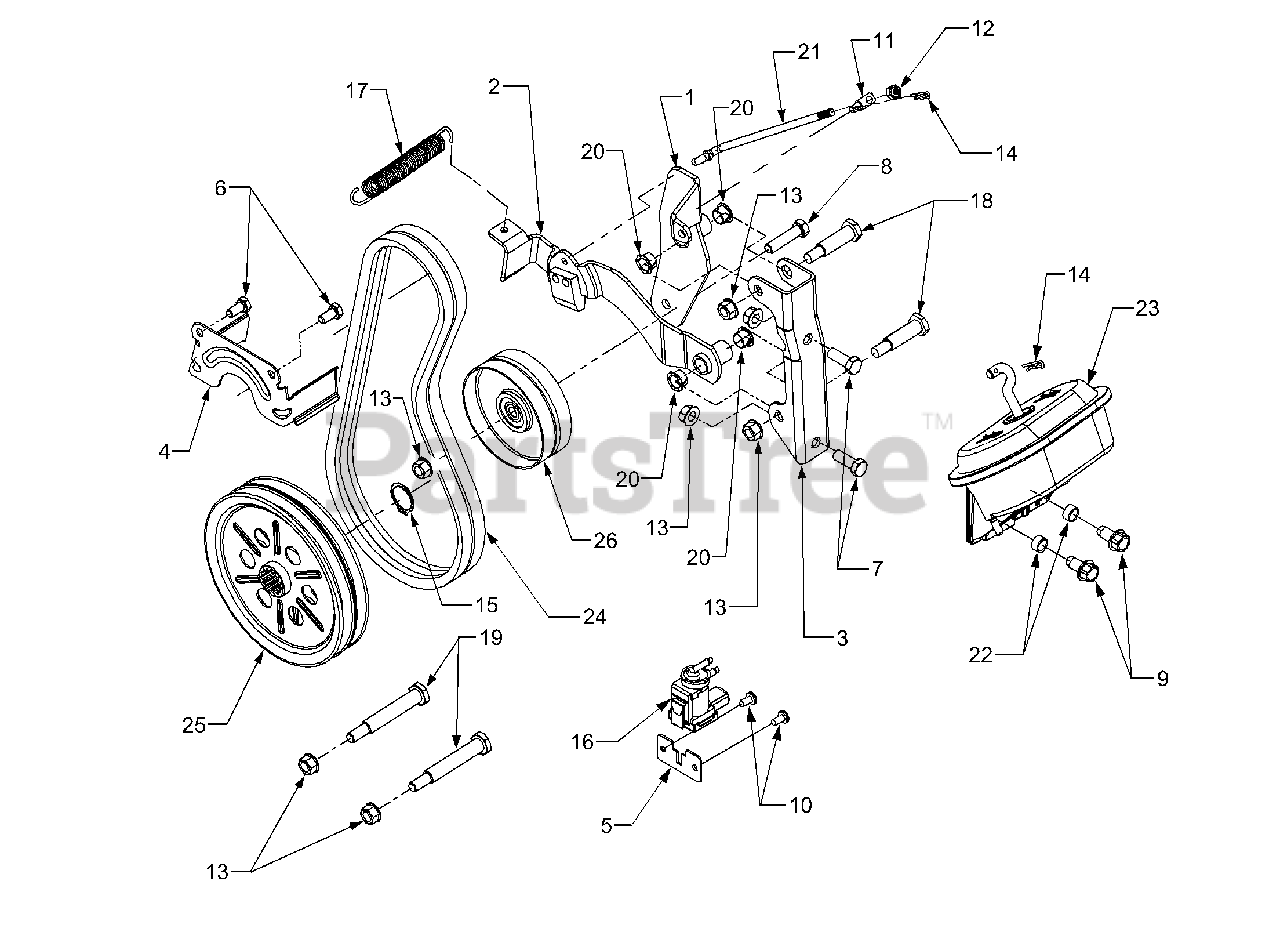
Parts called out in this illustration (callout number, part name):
1	Bracket, Idler
2	Bracket Assembly, Brake
3	Bracket, PTO Mounting
5	Bracket, Solenoid Mounting
6	Screw, Hex Cap 5/16-24 x .625 GR5
7	Screw, Hex Cap 3/8-16 x 1.0 GR5
8	Screw, Hex Cap 3/8-16 x 1.5 GR5
9	Screw, Hex Wash. Hd. Tapp 3/8-16 x .75
10	Screw, Phil. Hd. Tapp #12-14 x .5
11	Ferrule, Brake Adjustment
12	Nut, Hex Insert Lock, 1/4-20
13	Nut, Flange Lock, 3/8-16
14	Pin, Internal Cotter
15	Snap Ring, 1.0 Dia Shaft
16	Solenoid, Kit Vacuum Actuator
17	Spring, Extension, .530 x 4.74
18	Shoulder Screw, .498 x 1.45
19	Shoulder Screw
20	Bearing, Nylon Flange
21	Rod, PTO Brake
22	Spacer, .380 x .5 x .265
23	Vacuum Actuator
24	V-Belt, A-Section x 37.63 (Set of two belts)
25	Pulley, PTO Drive. 6.75-Double
26	Pulley, Flat Idler, 4.0
